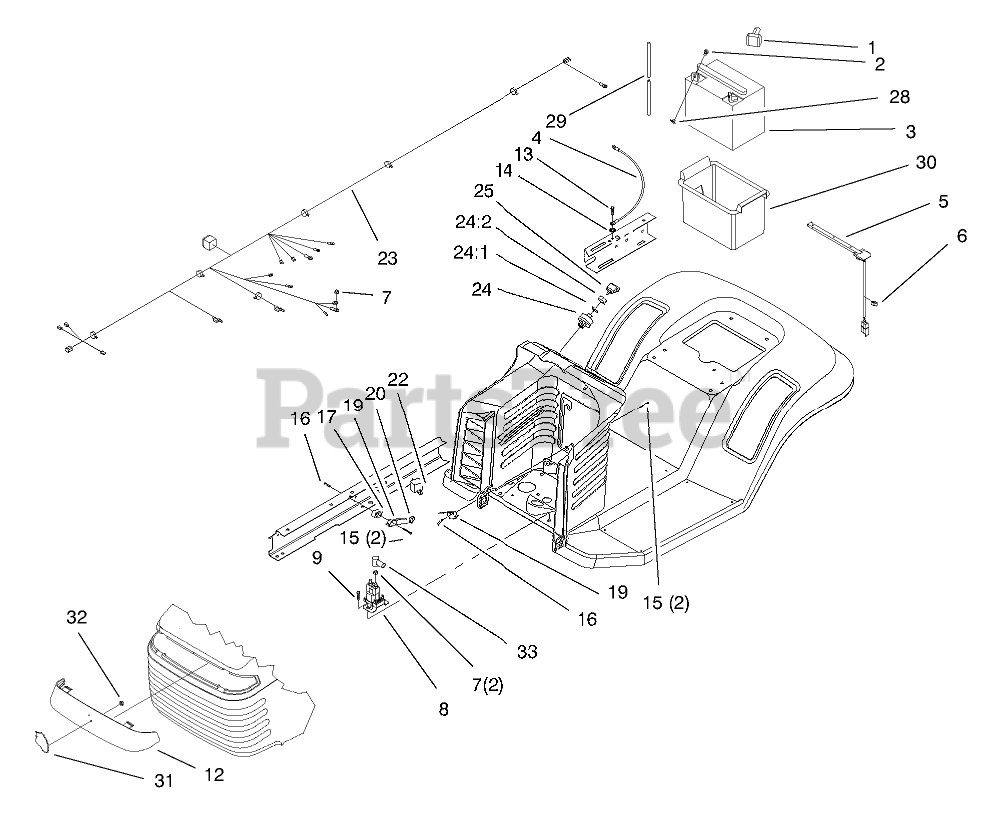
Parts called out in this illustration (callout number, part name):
1	BOOT-TERMINAL
2	SCREW-HH
3	Battery
4	WIRE ASM
5	SWITCH-SEAT
6	CLIP-RETAINER, WIRE
7	NUT-KEPS
8	Solenoid
9	SCREW-HWH
12	LENS-HEADLIGHT
13	SCREW-HWH
14	WASHER-LOCK/EXT
15	SCREW-HH
16	NUT-SPEED
17	SPACER
19	SWITCH-MICRO
20	PLUNGER-SEAL
22	RELAY
23	WIRE HARNESS
24	Key Switch ASM
24:1	WASHER-TOOTH, INTERNAL
24:2	NUT-HH
25	KEY-IGNITION
28	NUT-WING
29	TUBE-BATT DRAIN/80-2600
30	BOX-BATTERY
31	EMBLEM-GRILLE WHEELHORSE
33	BOOT-TERMINAL INSULATOR
